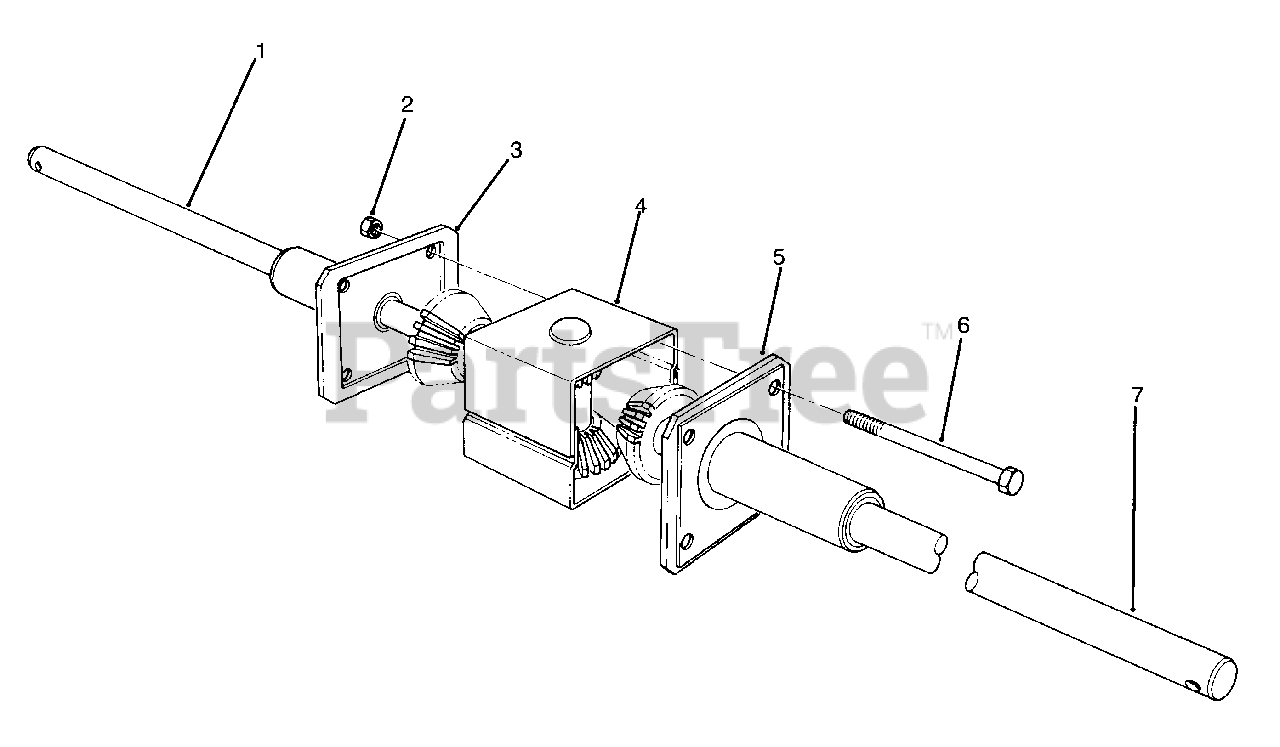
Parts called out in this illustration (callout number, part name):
1	Axle-R.H.
2	Nut-Lock
3	Cap-End, R.H.
4	Case-Gear, Transfer
5	Cap-End, L.H.
6	Screw-Cap Hex. Hd.
7	Axle-L.H.
